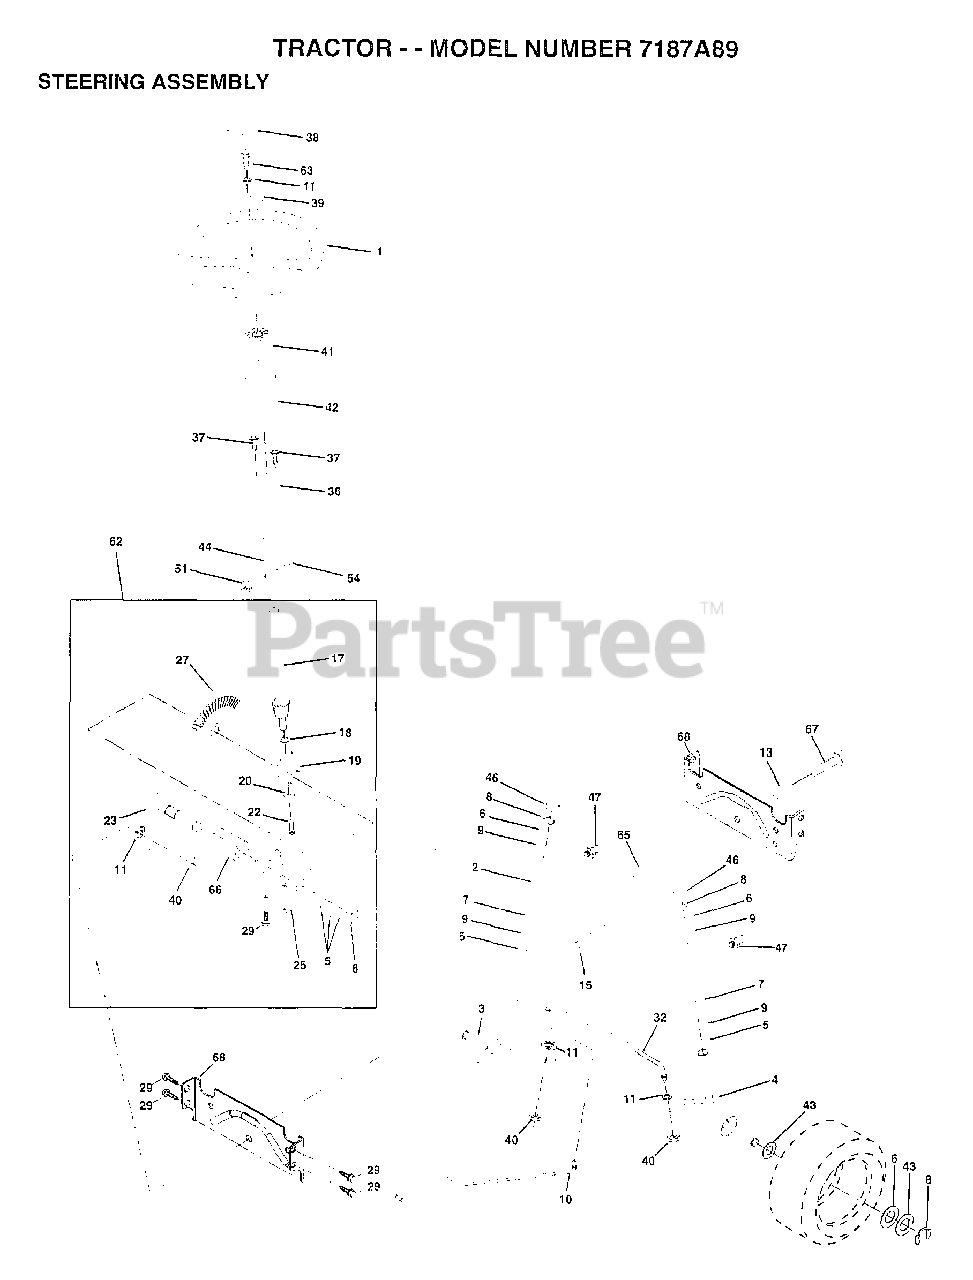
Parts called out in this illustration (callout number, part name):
1	WHEEL STR AYP BLK
3	"SPINDLE ASM,LH"
4	"SPINDLE ASM,RH"
6	WASHER
7	WASHER
8	RING
9	COL. SRTG. BEAR.
10	LINK.DRAG
11	LOCKWASHER
13	BEARING AXLE
15	"NUT-LOC,FLANGE LT"
17	SHAFT ASM STEERIN
18	THRUST WASHER
19	SUPPORT.SHAFT
22	SCREW HEX SOC1/4-
25	BRKT-STEERING
27	GEAR SECTOR
29	SCREW
32	ROD.ASM.TIE.BALL
36	BUSHING.STEERING
37	"SCREW-TT,10-32 FL"
38	CAP STEER AYP
39	WASHER T
40	GRIPCO NUT
41	ADAPTER LT
42	BOOT.STEER.PL
43	WASHER
44	EXT SHAFT STEERIN
46	CAP
47	ZERK M
51	NUT
54	BOLT
62	KIT STEERING ASM
63	BOLT
65	SPACER AXLE
66	"BEARING-ARM,PITMA"
67	BOLT
68	BRACE AXLE
